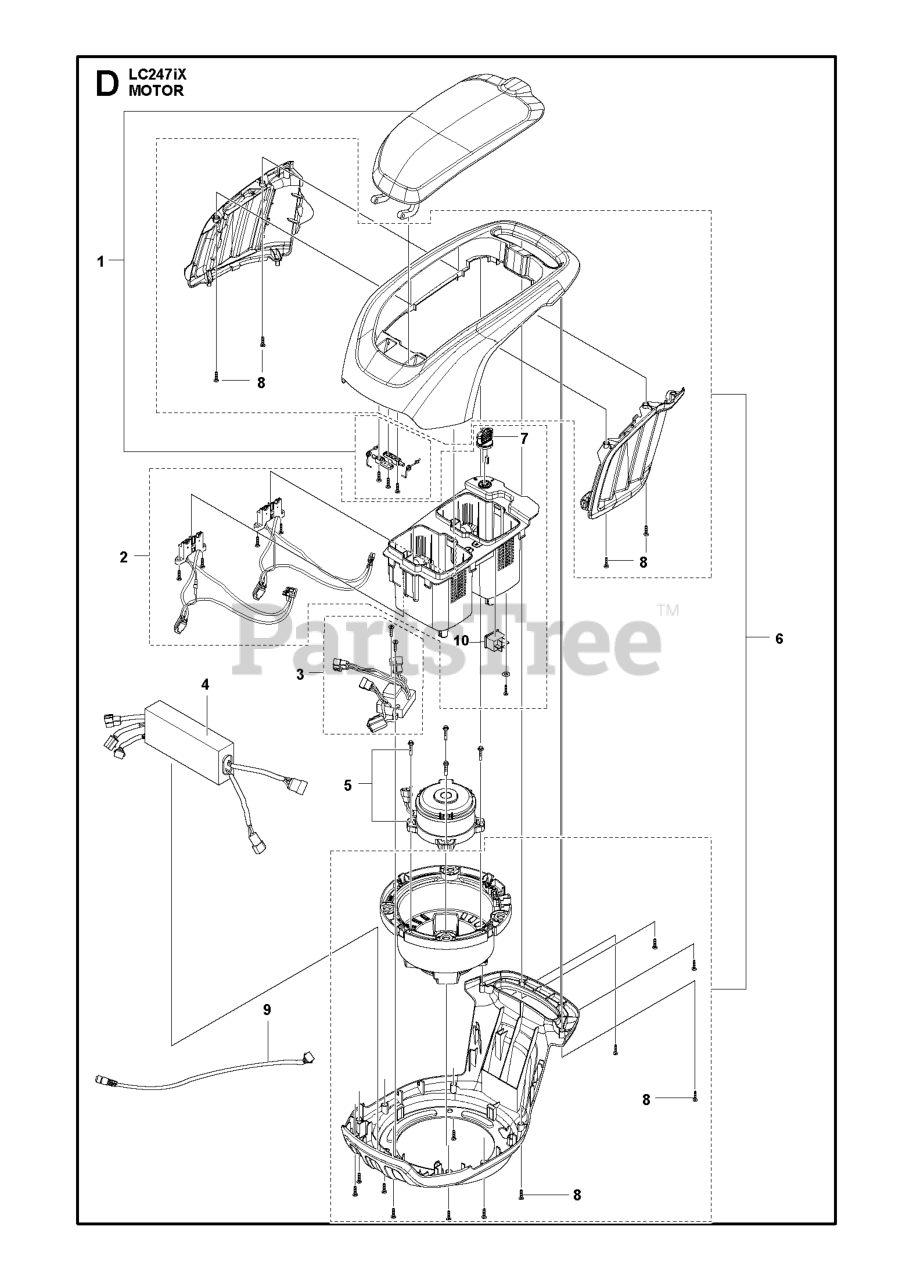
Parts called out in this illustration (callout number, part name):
1	LID ASSY SPARE PART ASSY LC247
2	BATTERY BOX SPARE PART ASSY LC
3	CONTACT PLATE SPARE PART ASSY
6	ENGINE HOOD ASSY POWER UNIT LC
7	KEY
8	SCREW SELF TAPPING DAYE# A2680
10	KEY SWITCH
